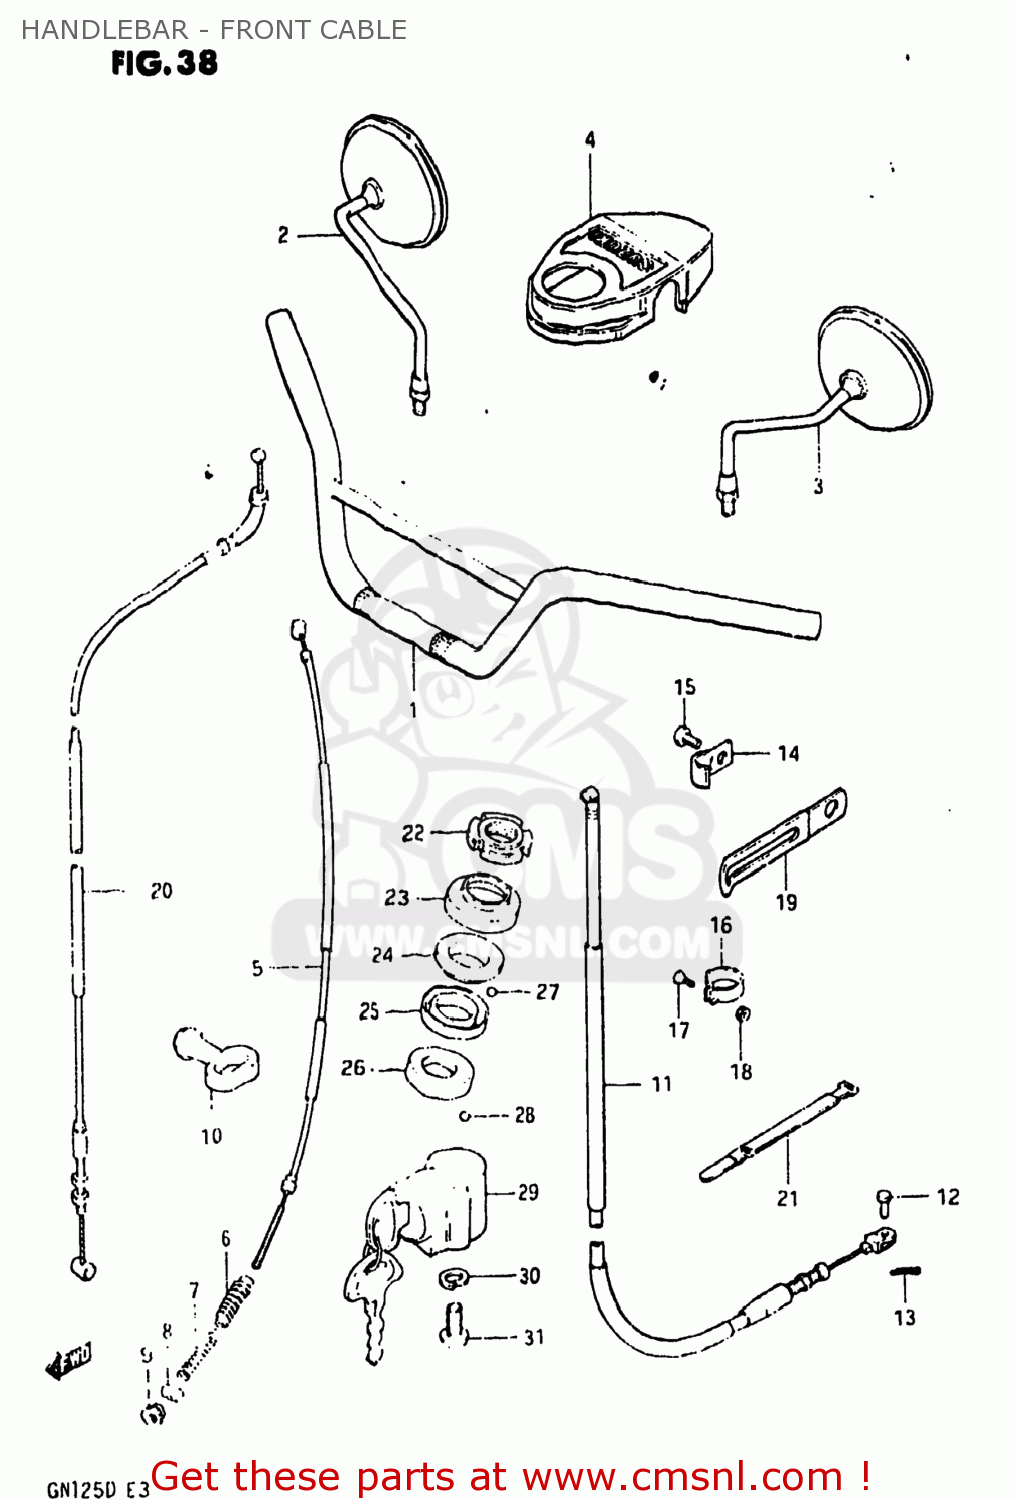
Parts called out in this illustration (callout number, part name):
1	HANDLEBAR
2	MIRROR ASSEMBLY,RIGHT
3	MIRROR ASSEMBLY,LEFT
4	COVER,STEERING HEAD
5	CABLE ASSEMBLY,FRONT BRAKE
6	SEAL,DUST(7X16X75)
7	SPRING
8	PIN,10X19
9	NUT
10	GUIDE,CABLE
11	CABLE ASSEMBLY,CLUTCH
12	PIN(L:15)
13	PIN
14	CLAMP,CLUTCH CABLE NO.1
15	SCREW
16	CLAMP,CABLE
17	SCREW
18	NUT
19	CLAMP
20	CABLE ASSEMBLY,THROTTLE
21	CLAMP
22	NUT,STEERING STEM(25X44X10)
23	DUST SEAL,STEERING UPR
24	RACE,STEERING OUTER UPR
25	RACE,STEERING INNER UPR
26	LACE,STEERING INNER LWR
27	BALL
28	BALL
29	LOCK ASSY,STEERING
30	LOCK WASHER
31	SCREW
